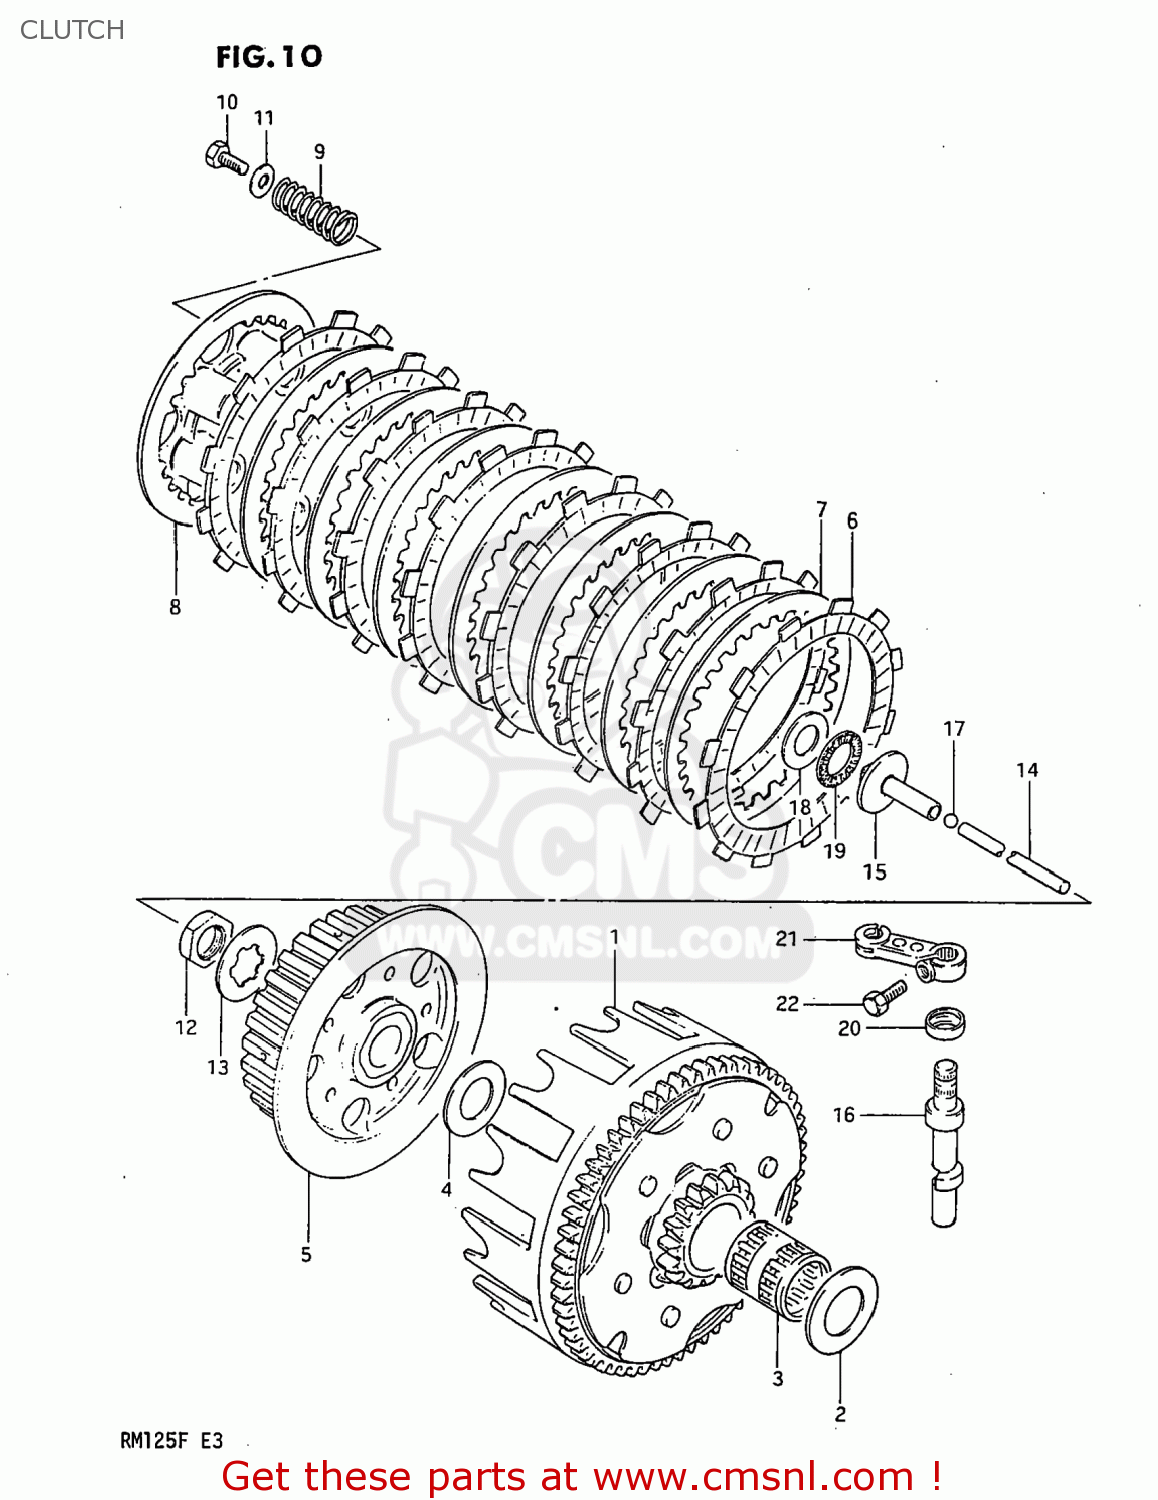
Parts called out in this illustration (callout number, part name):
1	GEAR ASSEMBLY,PRIMARY DRIVE
2	WASHER,THRUST
3	BEARING(20X25X26)
4	WASHER
5	HUB,CLUTCH SLEEVE
6	PLATE,CLUTCH DRIVE (MCA)
7	PLATE,CLUTCH DRIVEN (NAS)
8	PLATE,CLUTCH PRESSURE
9	SPRING
10	BOLT(5X16)
11	WASHER (5.5X16X1.2)
12	NUT
13	WASHER,LOCK
14	ROD,CLUTCH PUSH
15	PIECE,CLUTCH PUSH
16	SHAFT,CLUTCH RELEASE C
17	BALL
18	WASHER
19	BEARING(15X28X2)
20	OIL SEAL
21	ARM,CLUTCH RELEASE
22	BOLT, UPPER
